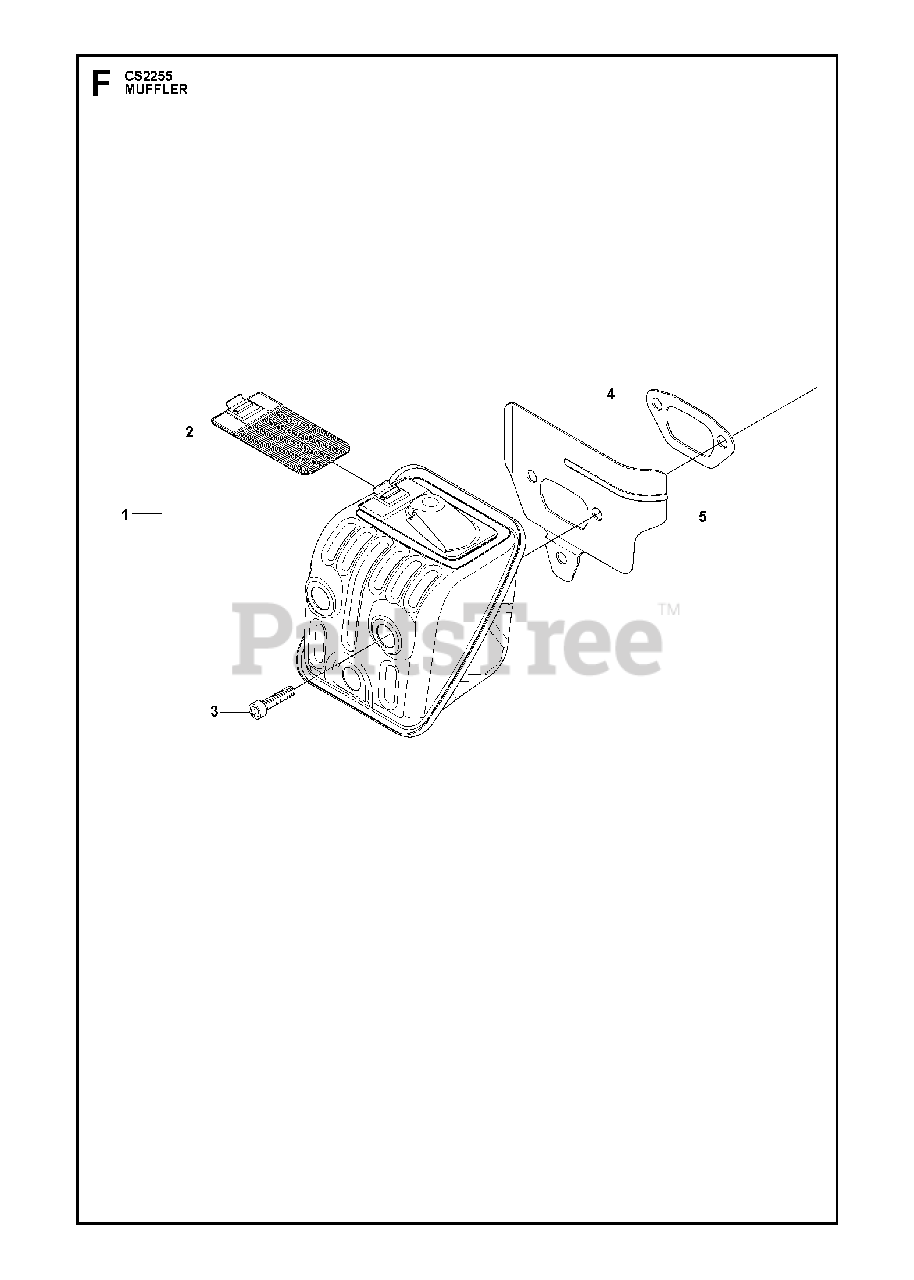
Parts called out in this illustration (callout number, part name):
1	%MUFFLER
2	SCREEN
3	SCREW MC6S 6X16
5	HEAT SHIELD
